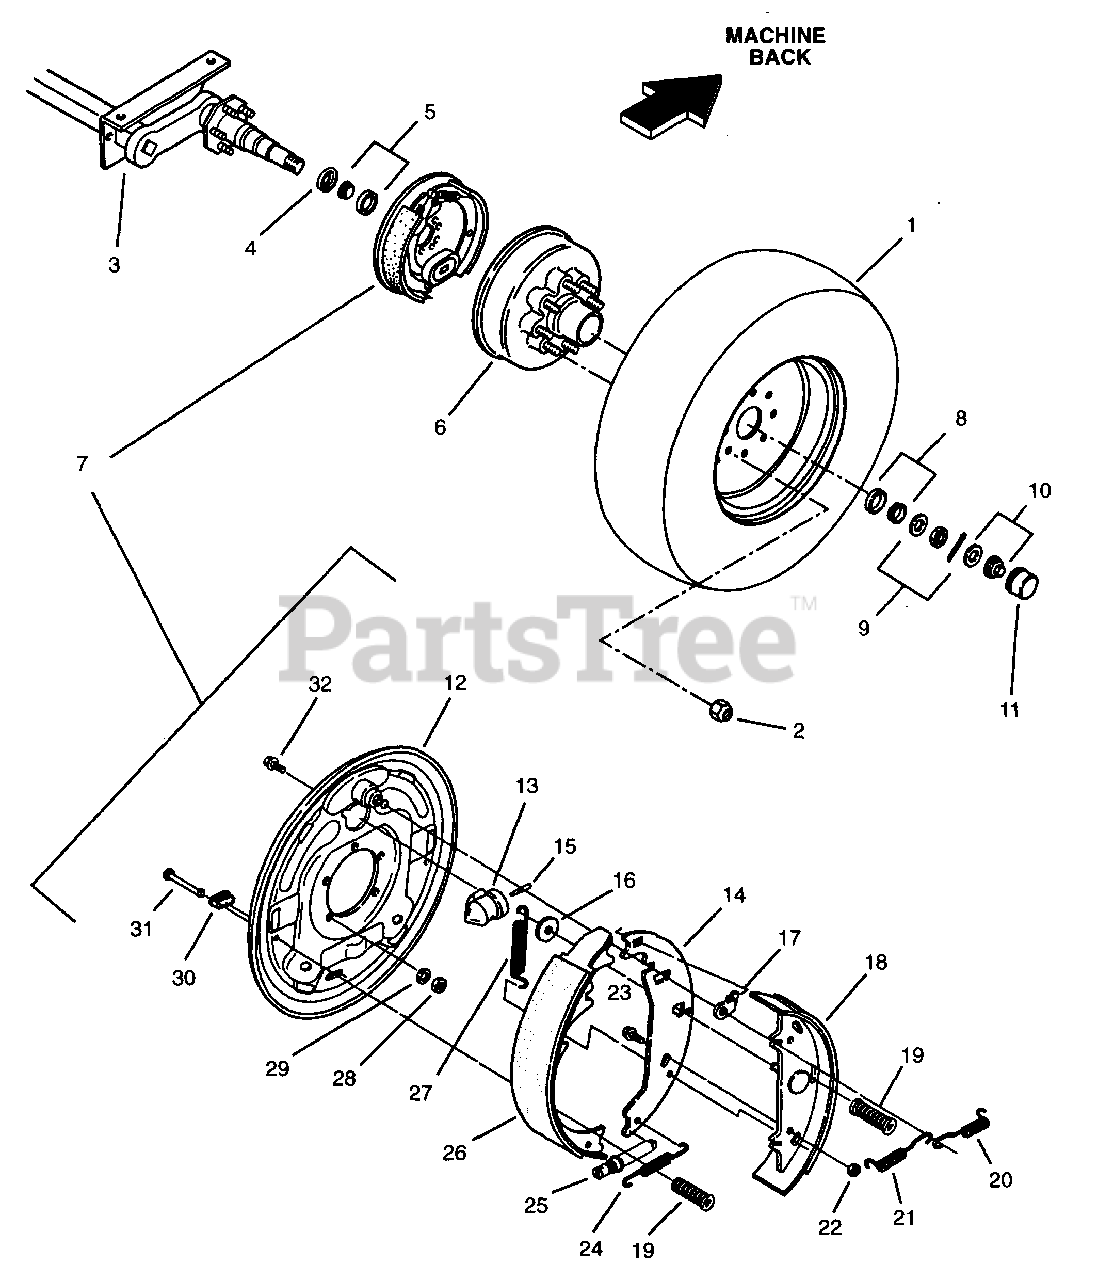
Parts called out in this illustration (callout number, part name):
1	Tire/Rim Assembly
2	Wheel Nut .50-20 13/16 Across FlatsAutomotive Type
3	Axle-6000lb 8 Lug Hydraulic Surge
4	Grease Seal
5	Inner Bearing Cup & Cone
5	Right Hand Brake Shoe & Lining Kit(Inc. 18,19,26,31)
5	Brake Spring Kit(Inc. 19,20,21,24,27)
5	Adjusting Screw & Spring Kit(Inc. 24,25)
6	Hub & Drum
7	Left Hand Brake Assembly(Contains Items12-32)
8	Outer Bearing Cup & Cone
9	Hardware Kit
10	Plug Kit
11	Grease Cap
12	Backing Plate Assembly
13	Left Hand Brake Cylinder Kit
14	Shoe Lever
